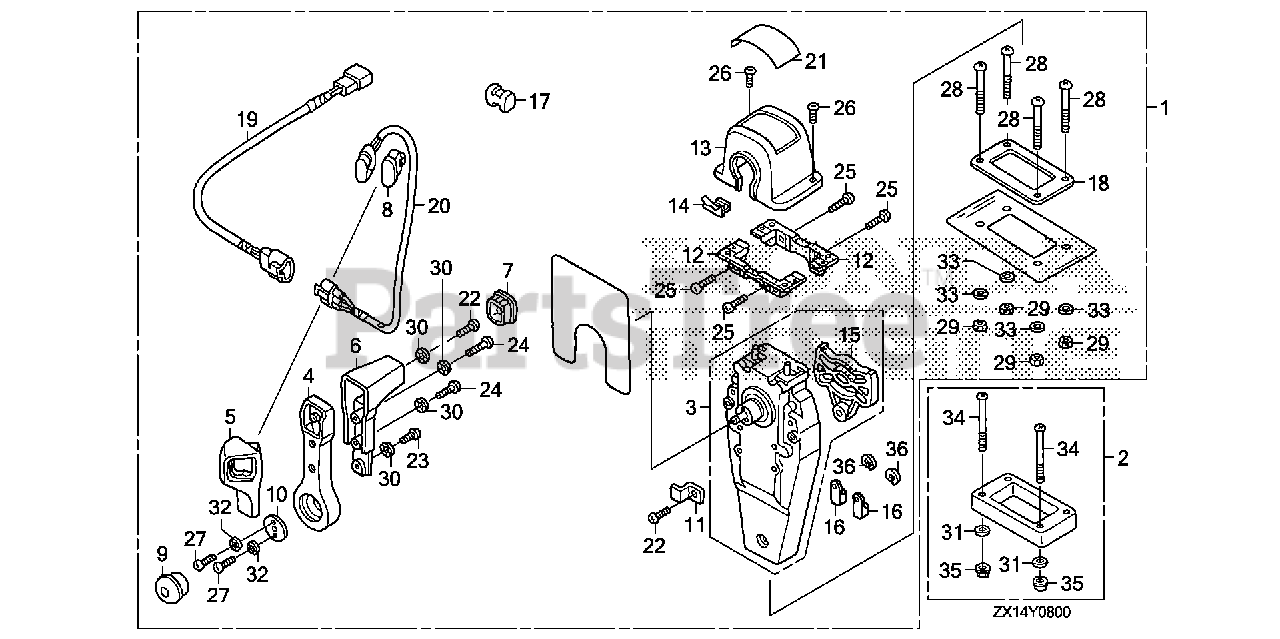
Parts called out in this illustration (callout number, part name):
1	BOX KIT, REMOTE CONTROL (TOP MOUNT SINGLE)(R)
1	BOX KIT, R. REMOTE CONTROL (TOP MOUNT SINGLE)
2	SPACER KIT, REMOTE CONTROL BOX (TOP MOUNT SINGLE)
3	HOUSING ASSY., L. (INNER) (TOP MOUNT)
4	HANDLE, REMOTE CONTROL
5	COVER, L. GRIP
6	GRIP, REMOTE CONTROL HANDLE
7	CAP, GRIP
8	CAP, SWITCH
9	BUTTON, THROTTLE
10	PLATE, HANDLE
11	PLATE, CABLE CLAMP
12	BRACKET, REMOTE CONTROL HOUSING
13	HOUSING, REMOTE CONTROL BOX
14	HOUSING, LEAD
15	PLATE, DWELL
16	TERMINAL, CABLE
17	SPACER, CABLE CLAMP
18	GASKET, SINGLE
19	SUB-HARNESS ASSY., POWER TRIM-TILT (A)
20	SWITCH ASSY., POWER TRIM-TILT (A)
21	MARK, REMOTE CONTROL (SINGLE)
22	SCREW, PAN (5X16)
23	SCREW, PAN (5X10)
24	SCREW, PAN (5X20)
25	SCREW, PAN (5X18)
26	SCREW, PAN (4X10)
27	SCREW, PAN (6X18)
28	SCREW, PAN (5X40)
29	NUT, HEX. (5MM)
30	WASHER, LOCK (5MM)
31	WASHER, PLAIN (5MM)
32	WASHER, LOCK (6MM)
33	WASHER, PLAIN (5MM)
34	SCREW, PAN (5X65)
35	NUT, HEX. (5MM)
36	E-RING (6MM)
